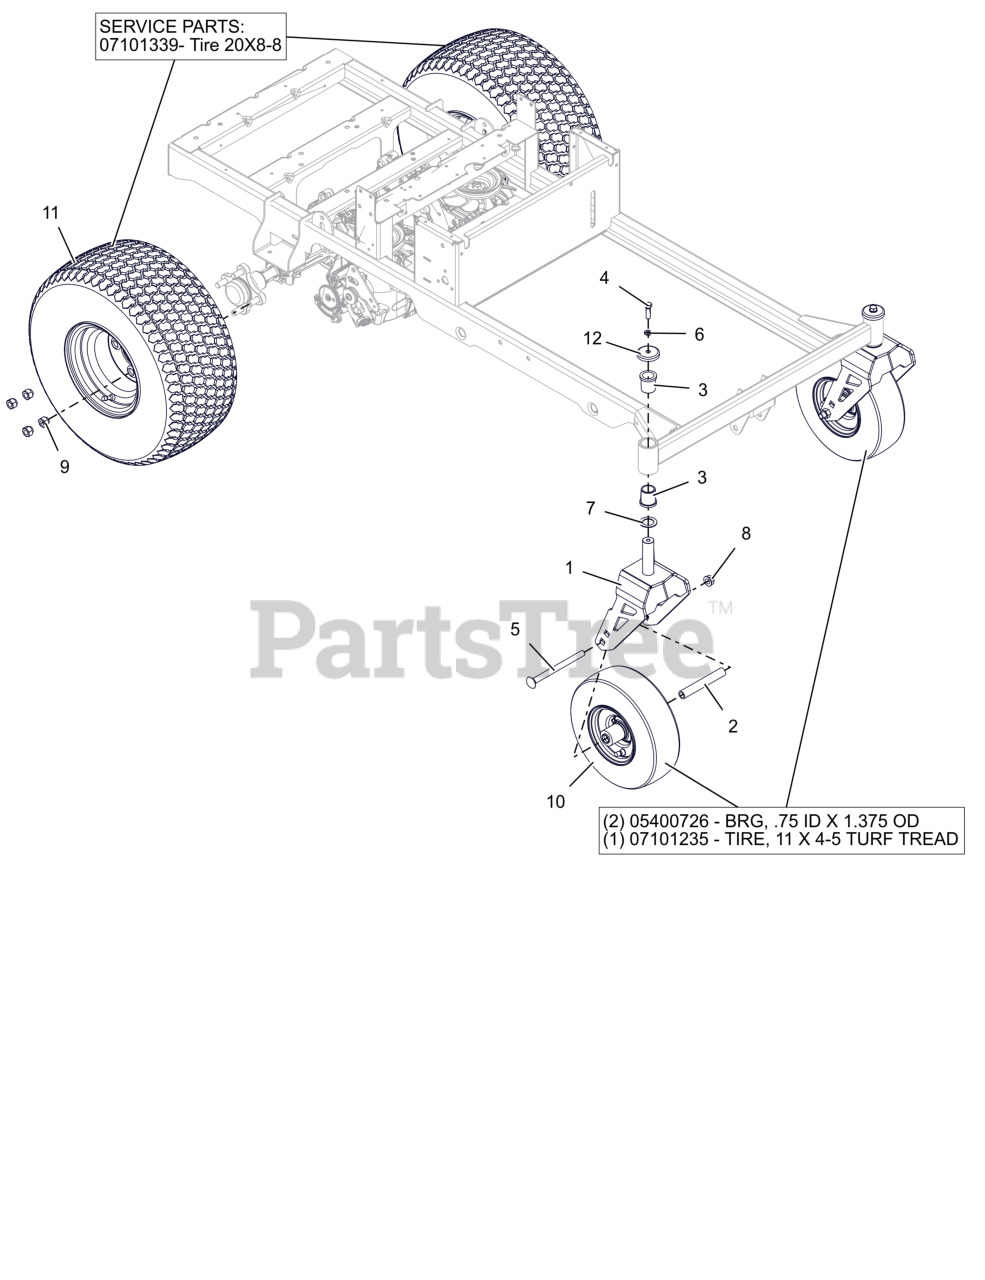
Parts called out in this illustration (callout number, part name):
1	WLDMT, CASTER FORK-XD (ORANGE)
2	SPACER, ROLLED WHEEL
3	BSHG-FLG 1.00X1.25X1.50X1.50
4	BLT, HEX .38-16X1.25 G5 ZCC
5	BLT, RHSN .50-13X6.50 G5 ZCC
6	WSHR,LK-REG .375X.094 ZCC
7	WSHR-HRD-THRS 1.007X1.542X.062
8	NUT-LK-CTR-FLG .500-13 GG ZCC
9	NUT, WHEEL .50-20 ZCC
10	ASM, WHL/TIRE 11X4.00-5
10	BRG, .75 ID X 1.375 OD
10	LAWN TIRE FRONT, 11/4-5 TURF TREAD
10	VALVE STEM ASS'Y
10	TIRE TUBE, 11/4.0-5 4 PLY TR87 90 BENT VALVE
11	ASSM TIRE\WHEEL, 20 X 8 -8
11	LAWN TIRE REAR, 4 PLY K505 20/8.00-8
11	TIRE TUBE 18/6.50/8.50/9.50-8, 20/8.00/10.00-8 4 PLY TR13 STRAIGHT VALVE
11	VALVE STEM ASS'Y
12	SHIELD- AXLE BEARING BLK
